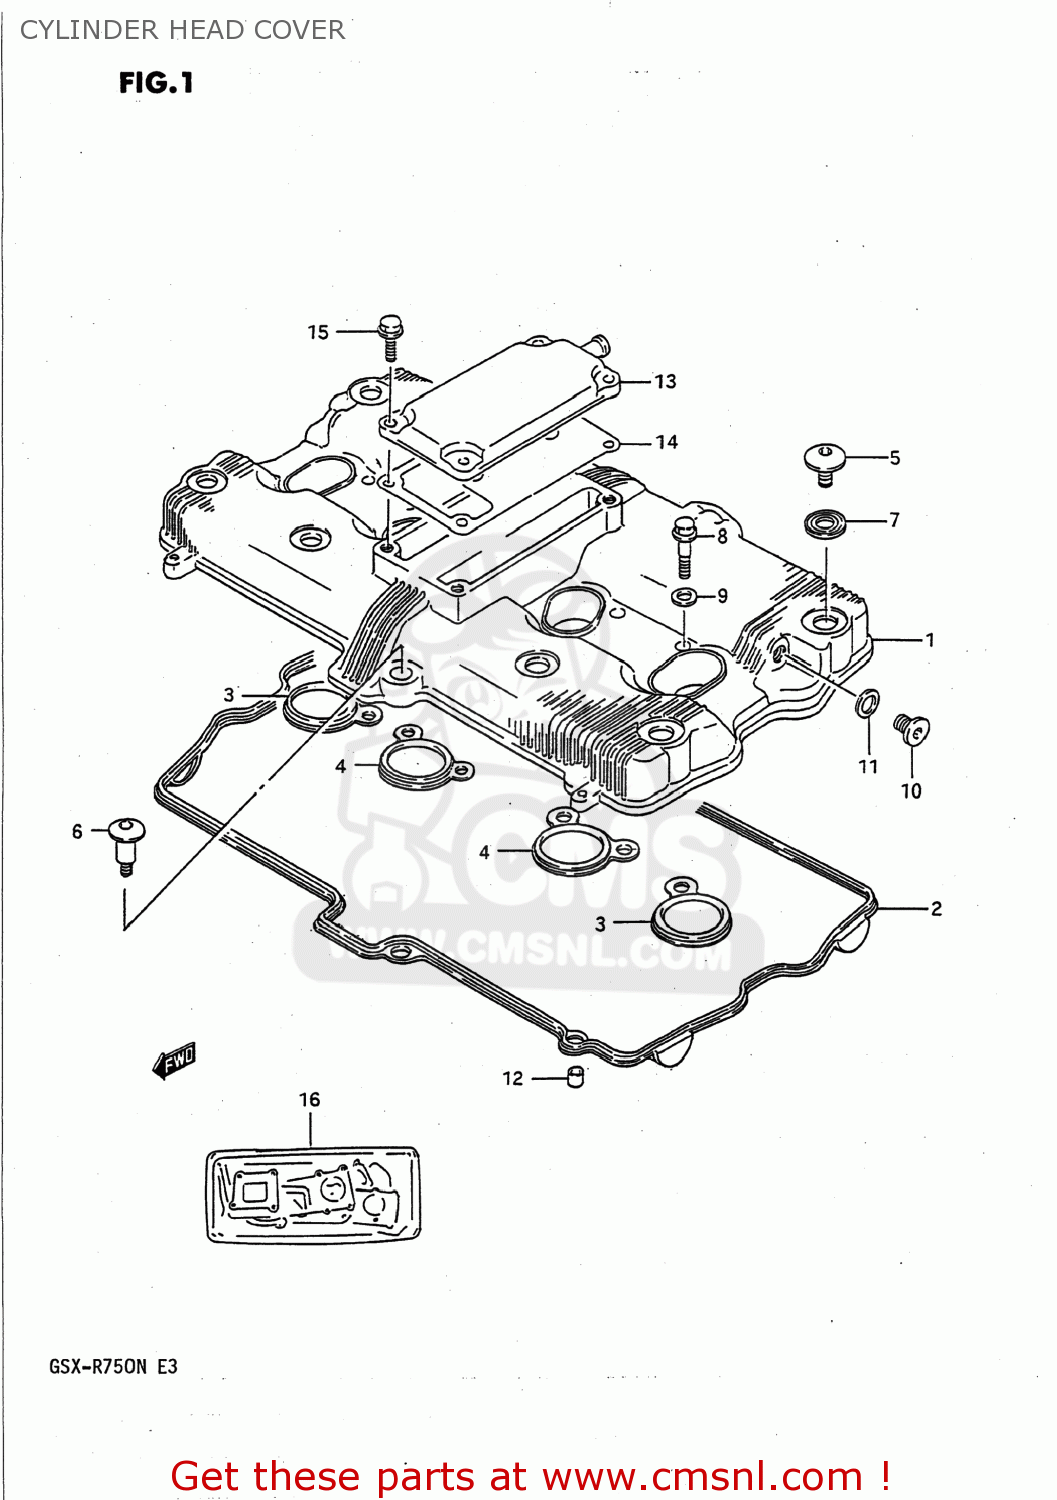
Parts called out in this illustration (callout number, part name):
1	COVER,CYLINDER HEAD
2	GASKET,CYLINDER HEAD COVER (NAS)
3	GASKET,HEAD COVER NO.2 (NAS)
4	GASKET,HEAD COVER NO.3 (NAS)
5	BOLT(7X17.5)
6	BOLT(7X31)
7	WASHER(10.6X25.5X2.3)
8	BOLT,UNION 8X35
9	GASKET 8.2X14X1 (NAS)
10	PLUG(L:12)
11	GASKET(12.1X16.2X3.7) (NAS)
12	PIN
13	COVER,BREATHER
14	GASKET,BREATHER COVER (NAS)
15	BOLT 6X20
16	GASKET SET
